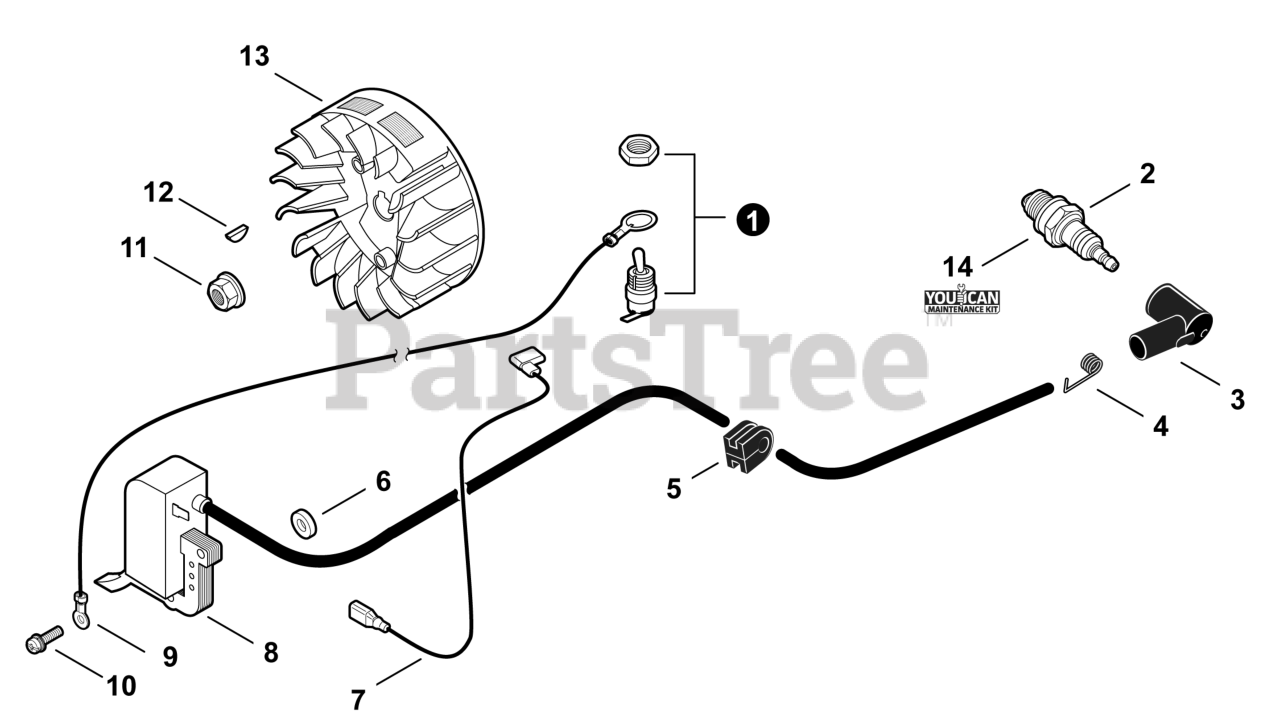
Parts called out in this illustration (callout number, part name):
1	SWITCH, ON-OFF
2	SPARK PLUG - BPMR8Y
3	CAP, SPARK PLUG
4	TERMINAL, SPARK PLUG
6	WASHER 5.2x12x3
7	LEAD - IGNITION L= 95
8	COIL, IGNITION
9	LEAD - GROUND L= 100
10	SCREW 5x22
11	NUT, FLANGE M8
12	KEY, WOODRUFF
13	FLYWHEEL
14	TUNE-UP KIT - YOUCANT
